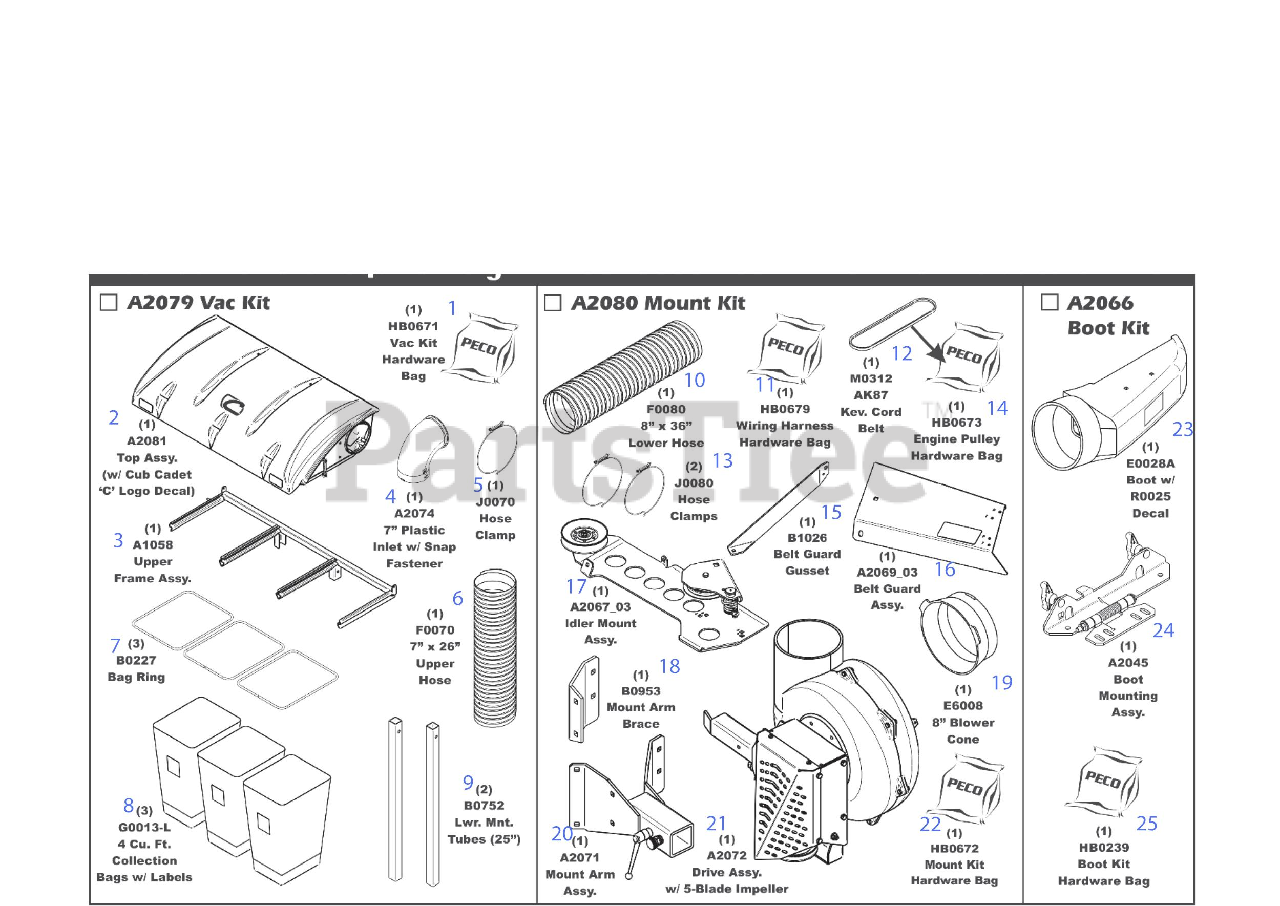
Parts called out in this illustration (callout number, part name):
1	Vac Kit Hardware Pack
2	Top Assembly W/C Logo
3	Upper Frame Assemb
4	7" Inlet W/Snap Fastener
5	Hose Clamp 7"
6	7" X 26" Upper Hose
8	4 Cu. Ft. Collection Bags W/Logo
9	Lower Mount Tubes 25"
10	8" X 36" Lower Hose
11	Wiring Harness Hardware Bag
12	Ak87 Kevlar Cord Belt
13	Hose Clamp 8"
14	Engine Pulley Hardware Bag
15	Belt Guard Gusset
16	Belt Guard Assembly
17	Idler Mount Assembly
18	Mount Arm Brace
19	8" Blower Cone
20	Mount Arm Assembly
21	Drive Assembly W/5 Blade Impeller
22	Mount Kit Hardware Bag
23	Boot With Decals
24	Boot Mounting Assembly
25	Boot Kit Hardware Bag
